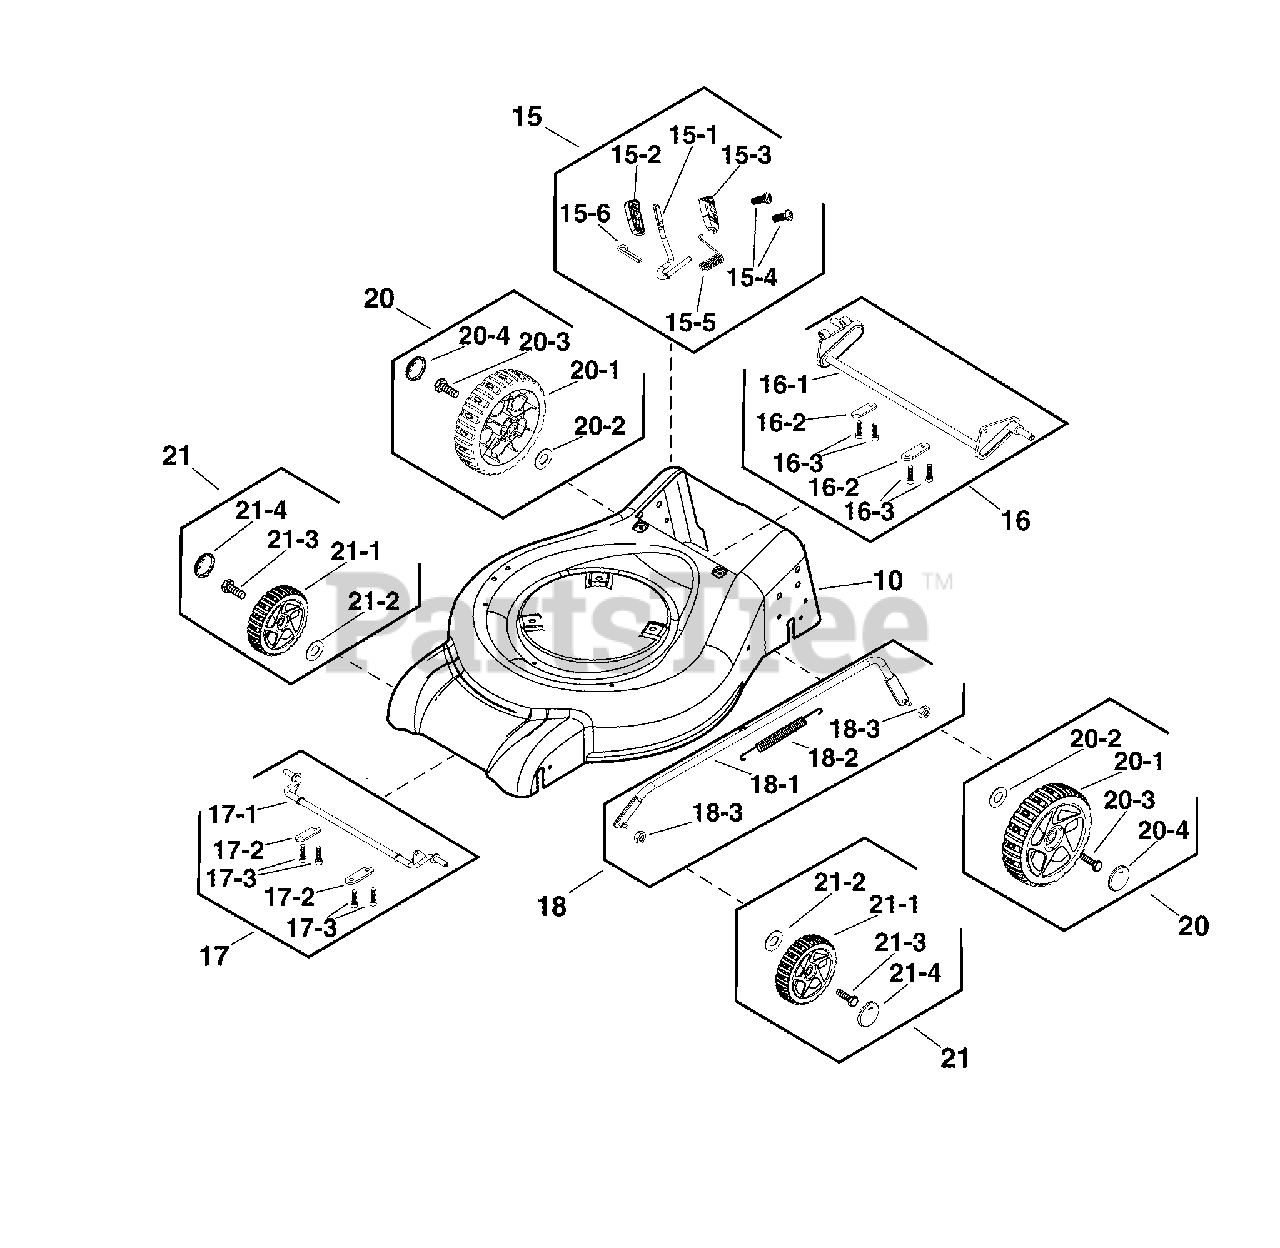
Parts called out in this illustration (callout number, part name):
10	MOWER DECK
15	KIT, HEIGHT ADJUST
15-1	BAR
15-2	HOUSING, Left
15-3	HOUSING, Right
15-4	SCREW
15-5	SPRING
15-6	PIN, Cotter
16	KIT, REAR AXLE
16-1	REAR AXLE
16-2	TAB
17	KIT, FRONT AXLE
17-1	FRONT AXLE
17-2	TAB
18	KIT, HEIGHT ADJUST ROD
18-1	HEIGHT ADJUSTMENT
18-2	SPRING
18-3	NUT
20	KIT, Wheel, 10", NA & EU
20-1	WHEEL
20-2	WASHER
20-3	BOLT
20-4	COVER, Wheel
21	KIT, Wheel, 8"
21-2	WASHER
21-3	BOLT
21-4	COVER, Wheel
